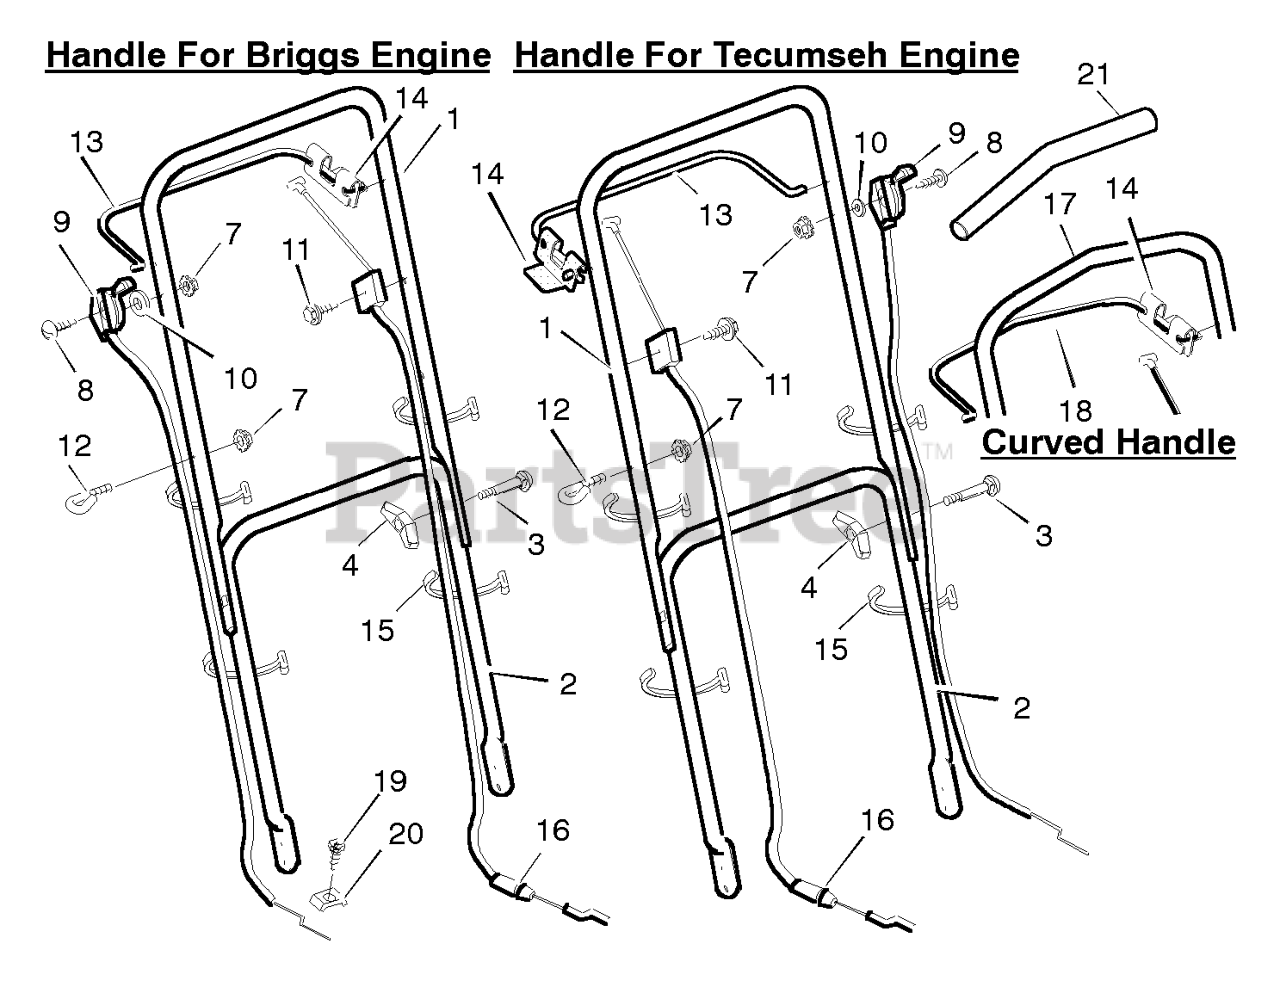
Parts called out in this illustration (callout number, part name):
1	Handle, Upper-Straight (Black)
2	Handle, Lower (Black)
4	Knob, Plastic
7	Locknut
9	Throttle Control
10	Washer
12	GUIDE, ROPE
13	Stop Lever - Straight
14	Bracket, Stop Lever
15	Fastener, Cable
16	Engine Stop Cable *
17	Handle, Upper- Curved (Black)
18	Stop Lever - Curved
19	Screw *
20	Clamp
21	Foam
